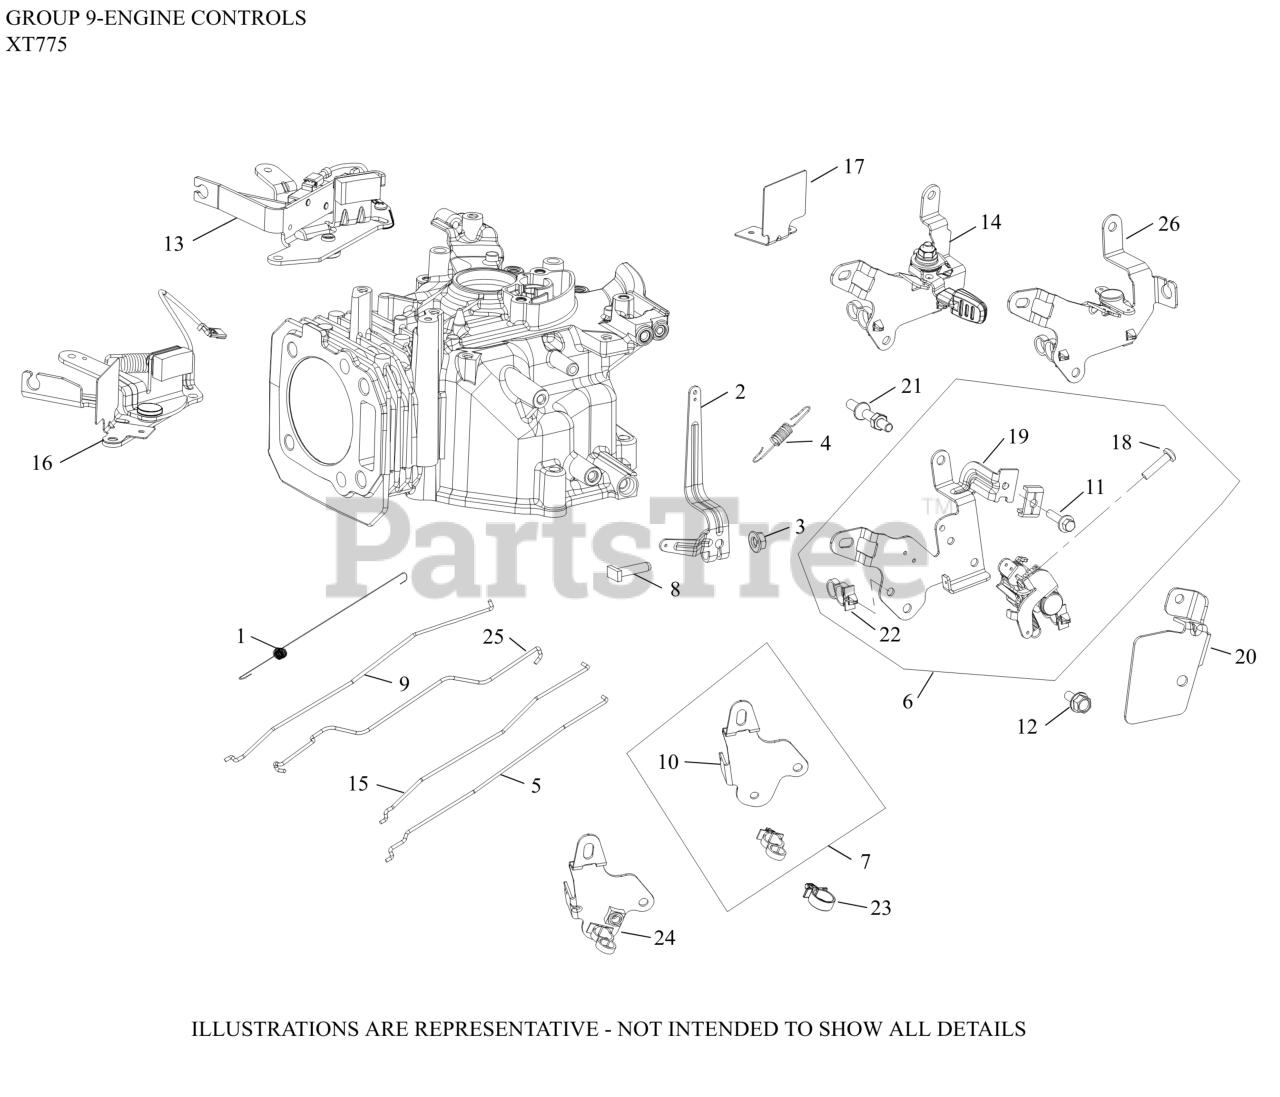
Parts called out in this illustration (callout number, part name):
1	SPRING, LINKAGE
2	LEVER, GOVERNOR-USE 14 090 37-S
4	SPRING, GOV (3301-3800 RPM)
5	LINKAGE, CHOKE
8	SCREW, RECTANGLE HEAD (M6)
14	CNTRL ASSY,NON-REMOTE MAN CHOKE
15	LINKAGE, GOVERNOR
